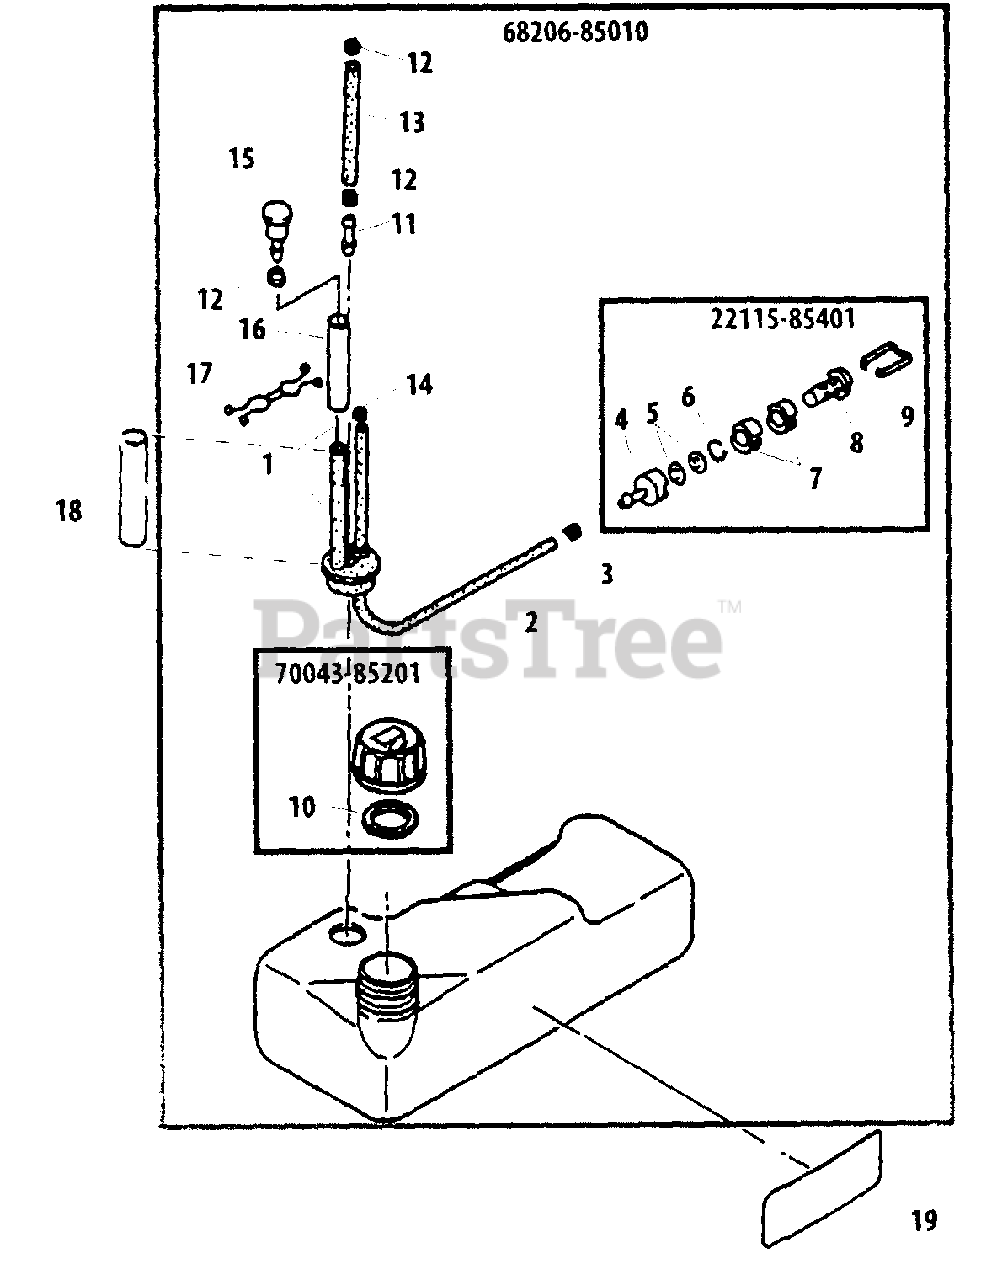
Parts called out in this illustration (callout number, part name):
1	PIPE ASSY
2	TUBE
3	RING, RETAINING - 6
4	WEIGHT, FUEL FILTER
5	SCREEN, FILTER
6	RING, RETAINING
7	FILTER, FUEL
8	CASE, FILTER
9	CLIP, FILTER
10	GASKET, CAP
11	CONNECTOR, PIPE
12	RING, RETAINING - 6
13	TUBE - 5X3X110
14	CLIP
15	VENT, FUEL TANK
16	TUBE
17	CLIP
18	SLEEVE X12 X X11 X L70
19	LABEL - MODEL
22115-85401	FILTER, FUEL
68206-85010	FUEL TANK ASSY
70043-85201	CAP ASSY
